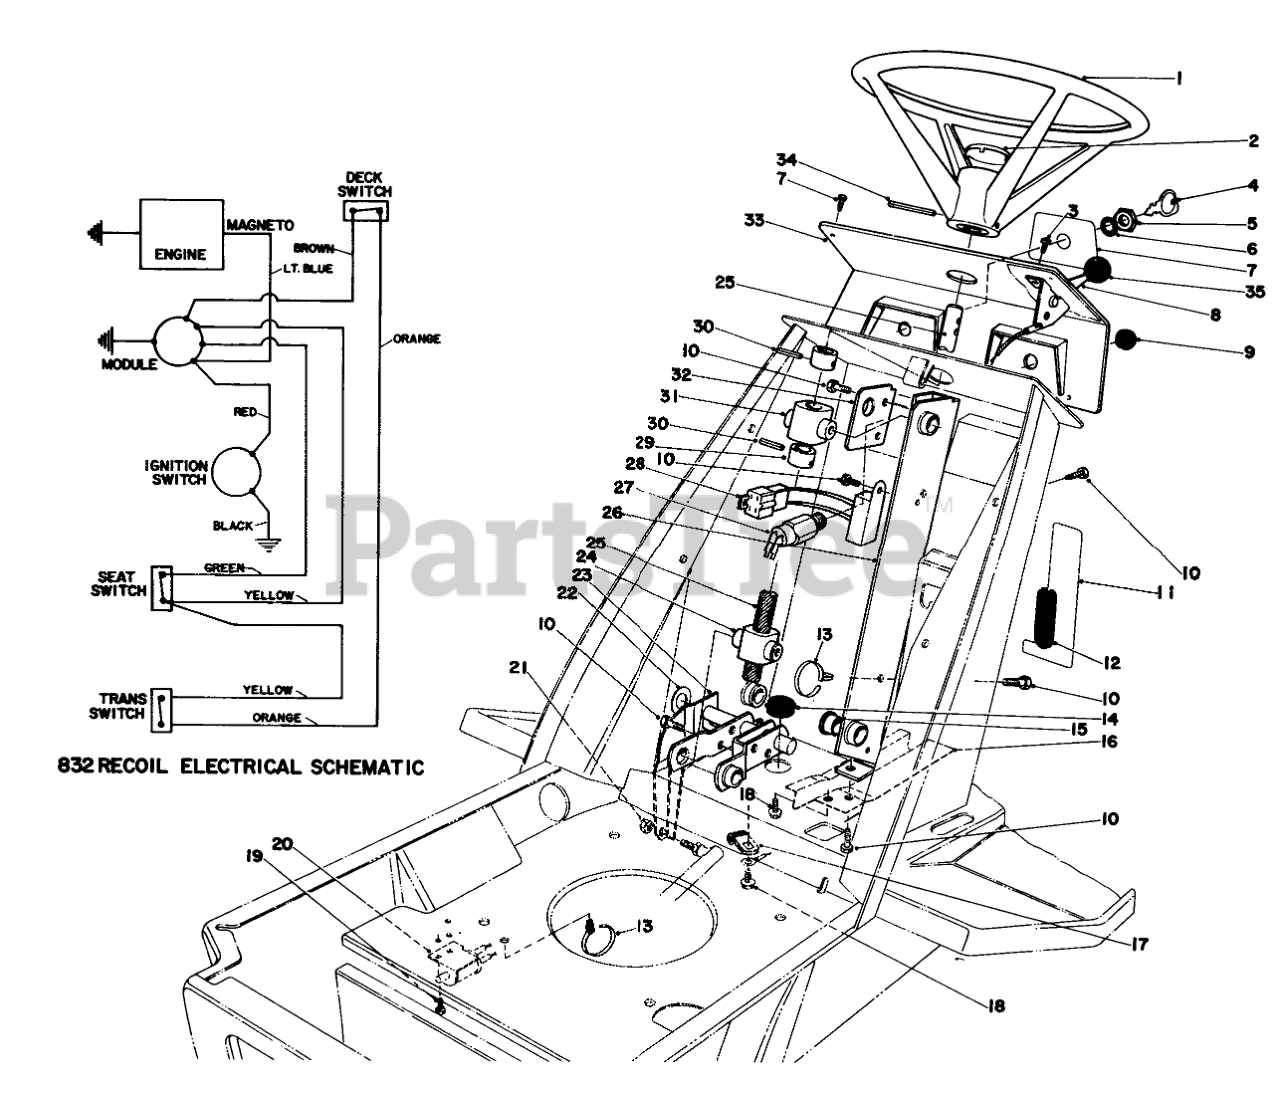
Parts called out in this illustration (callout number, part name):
1	Steering Wheel
2	Insert-Steering Wheel
3	SCREW-HWHTF
4	Key
5	NUT-HH
6	WASHER-TOOTH, INTERNAL
7	DASH PANEL DECAL
8	THROTTLE CONTROL
9	Domed Plug
10	SCREW-HWHTF
11	Decal-Deck
12	EDGE MOULDING
13	TIE-MOUNT, PUSH
14	GROMMET
15	BEARING-FLANGE
16	WIRE HARNESS SHLD B
17	CLIP-FUEL LINE
18	SCREW-HWH
19	SCREW-TAPTITE
20	DECK INTERLOCK SWITCH
21	Nut
22	WASHER
23	STEERING LINK WA BO
24	FOLLOWER STEER SHAFT
25	STEERING SHAFT
26	STRG BRKT B
27	SWITCH-ON / OFF
28	INTERLOCK MODULE
29	STRG SHAFT COLLAR
30	PIN-SPRING
31	BRG STEERING SHAFT
32	STRG BRG SUPPORT
33	DASH PANEL
34	PIN-ROLL
35	KNOB-CONTROL
